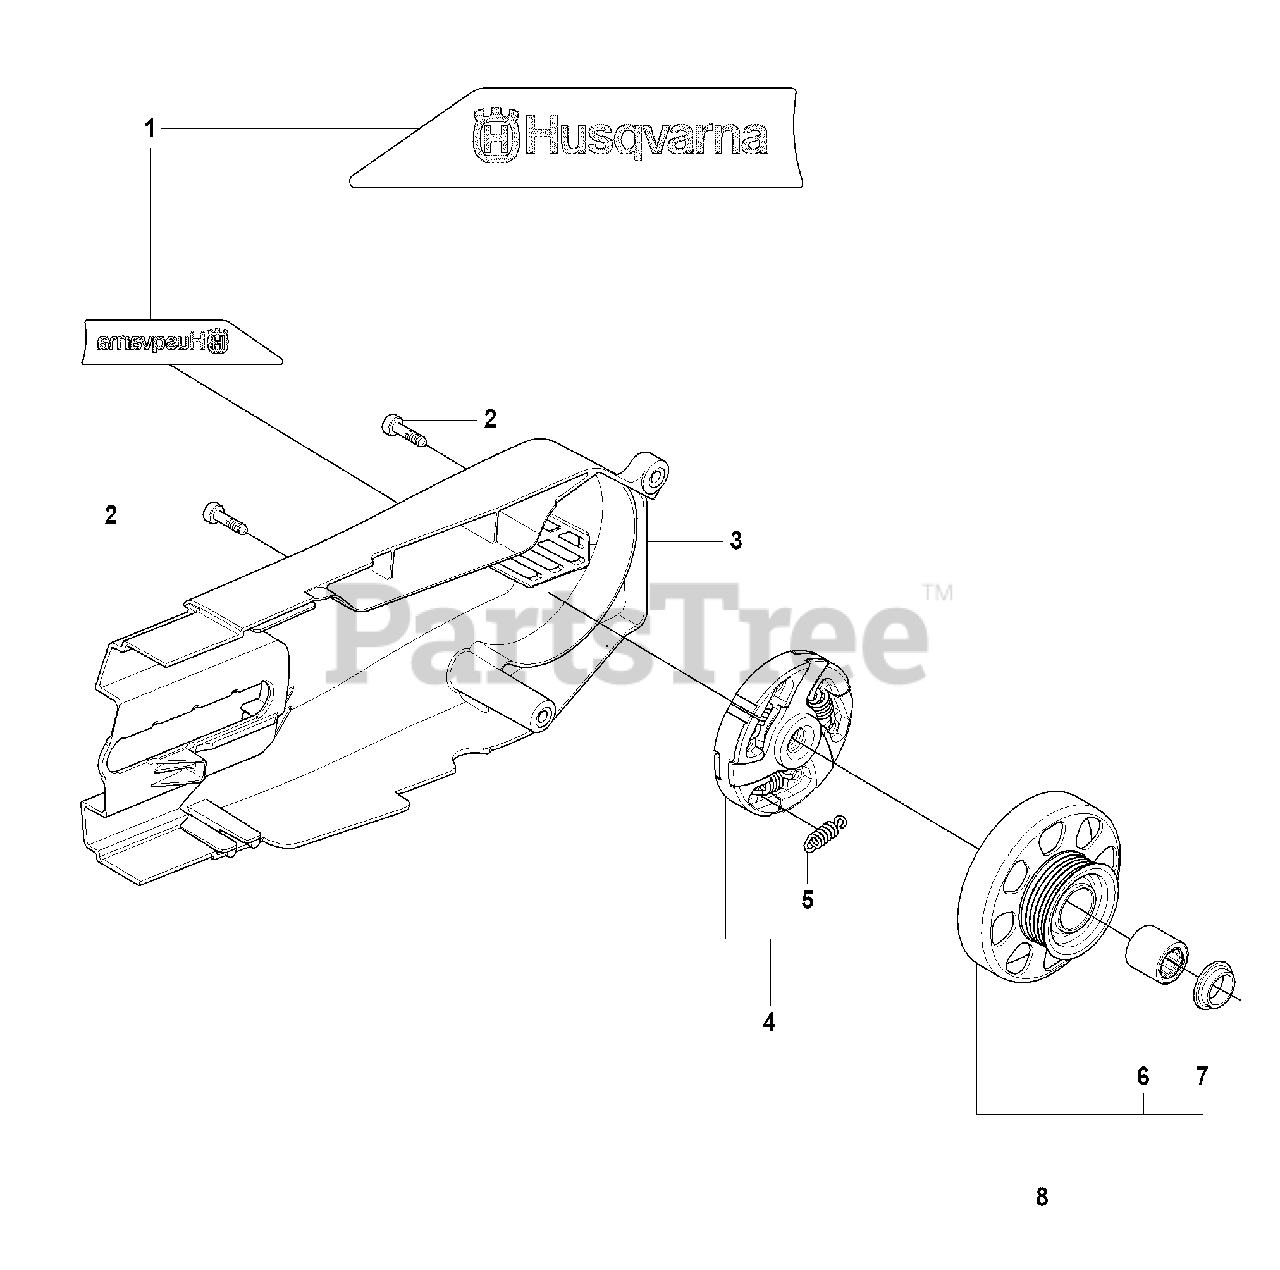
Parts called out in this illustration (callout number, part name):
3	BELT GUARD
4	CLUTCH ASSY
5	CLUTCH SPRING
6	NEEDLE BEARING
8	DRIVING PULLEY ASSY
